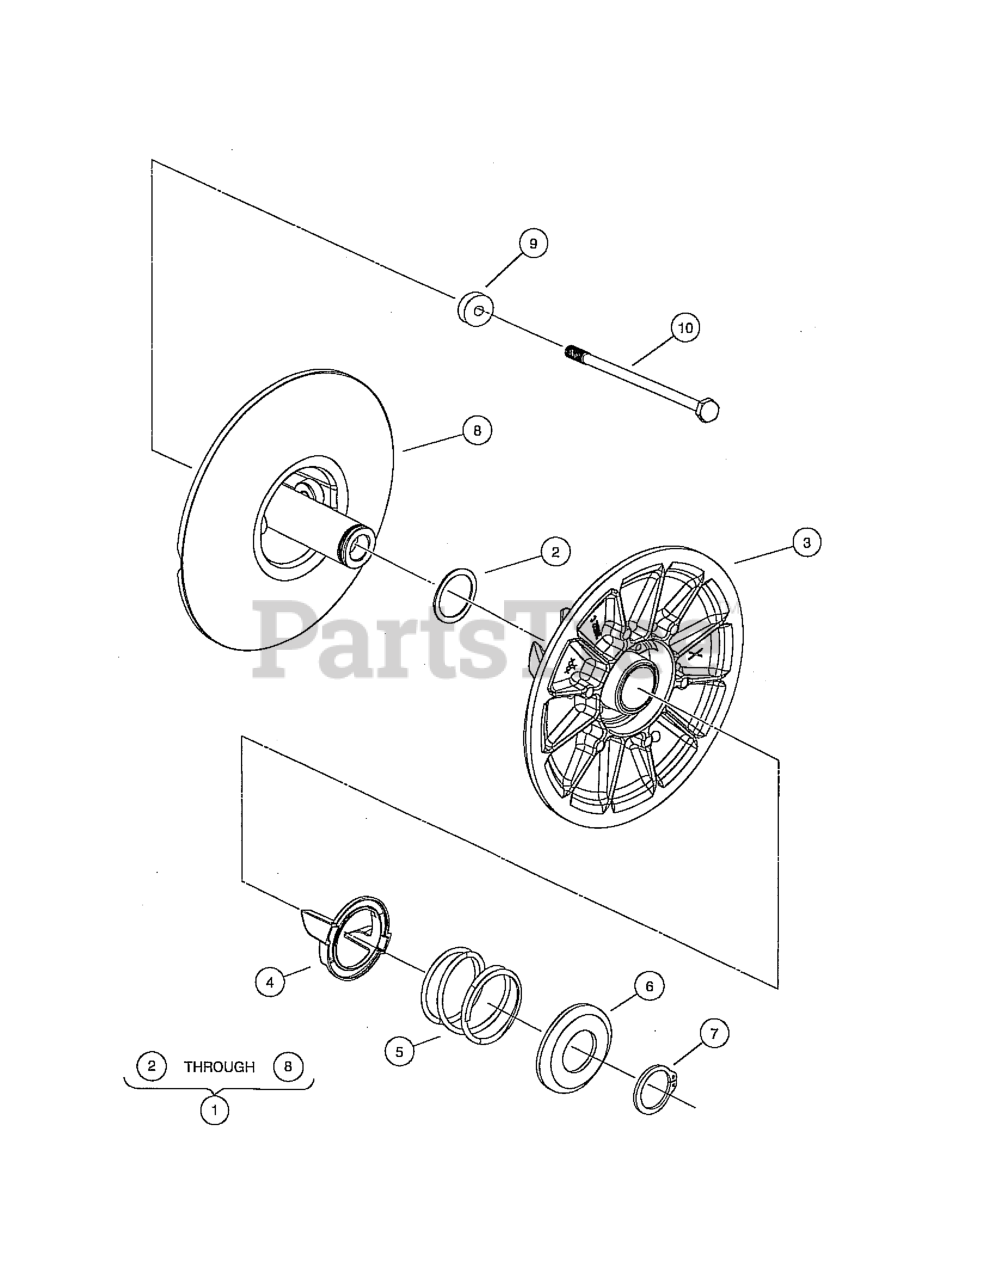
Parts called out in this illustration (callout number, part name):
1	CVT, SECONDARY
2	WASHER, THRUST, 1.53 X 1.92
4	RETAINER, SPRING, INNER
5	SPRING, COMPRESSION, SECONDARY
6	RETAINER, SPRING, OUTER
7	RING, RETAINING, EXTERNAL
9	WASHER, STEPPED, CVT SECONDARY
10	BOLT, M10 X 1.5 X 100 LOCTITE
